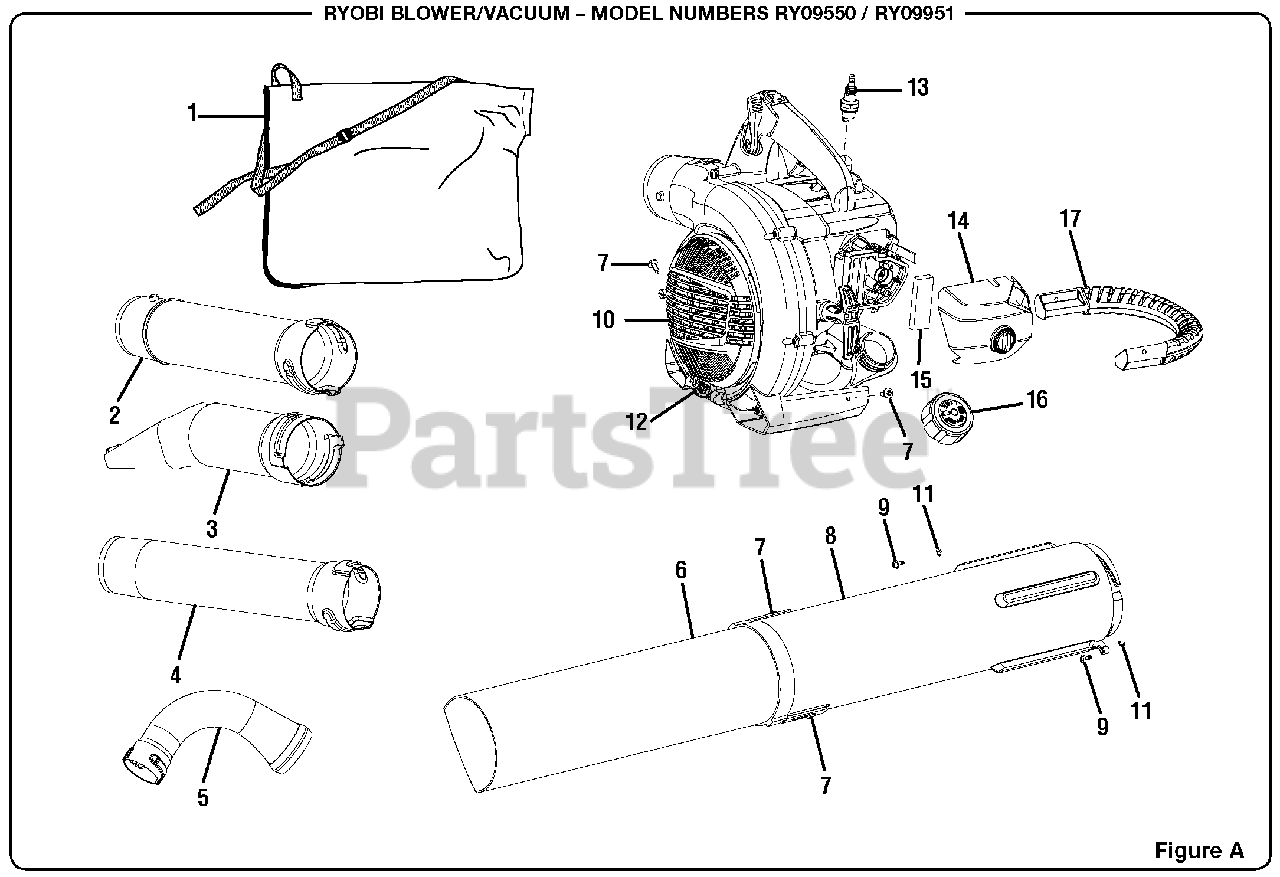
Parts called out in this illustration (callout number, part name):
1	Vacuum Bag w/Shoulder Strap
2	Upper Blower Tube
3	High Velocity Nozzle w/Leaf Scraper
4	Sweeper Nozzle
5	Vacuum Bag Adaptor
6	Lower Vacuum Tube
7	Screw (10-14 x 1/2 in.)
8	Upper Vacuum Tube
9	Screw (1/4-20 x 3/4 in.)
10	Vacuum Door
12	Vacuum Door Spring
13	Spark Plug (RCJ6Y)
14	Air Filter Cover
16	Fuel Cap Assembly
17	Vacuum Handle
